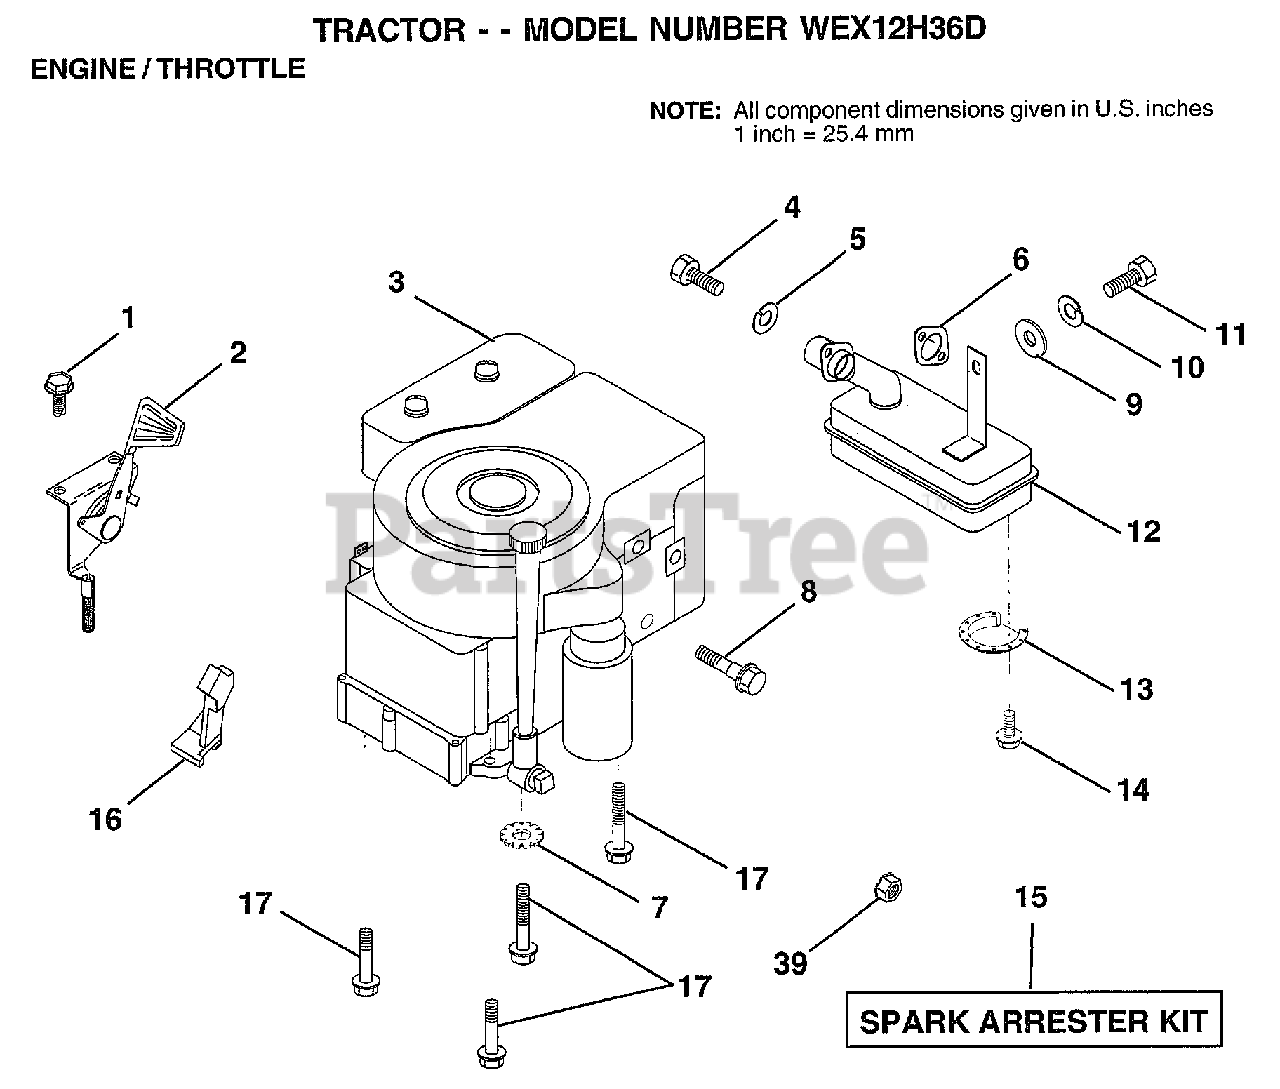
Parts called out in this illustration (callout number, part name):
1	SCREW LT
4	SCREW
5	LOCKWASHER
7	LOCKWASHER
8	BOLT T
10	LOCKWASHER
12	MUFFLER
13	DEFLECTOR.222573
16	"STOP,DASH THROTT"
17	SCREW LT
39	NUT
